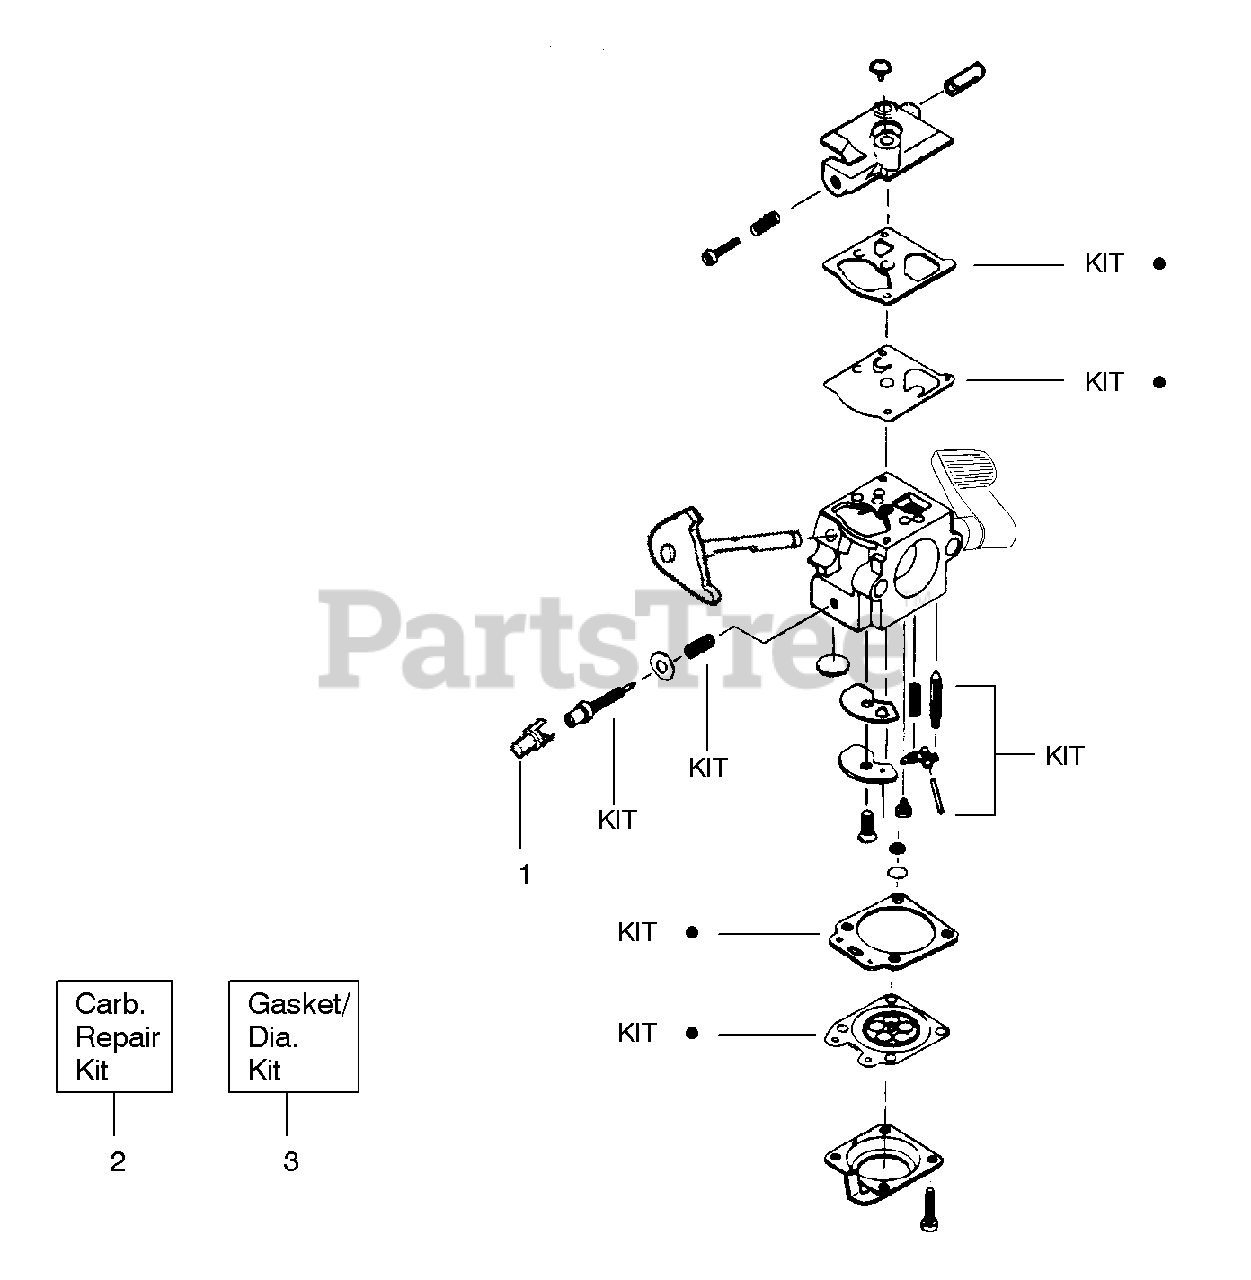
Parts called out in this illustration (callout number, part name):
1	Limiter Cap
2	Carburetor Repair Kit
3	Gasket Diaphragm Kit
